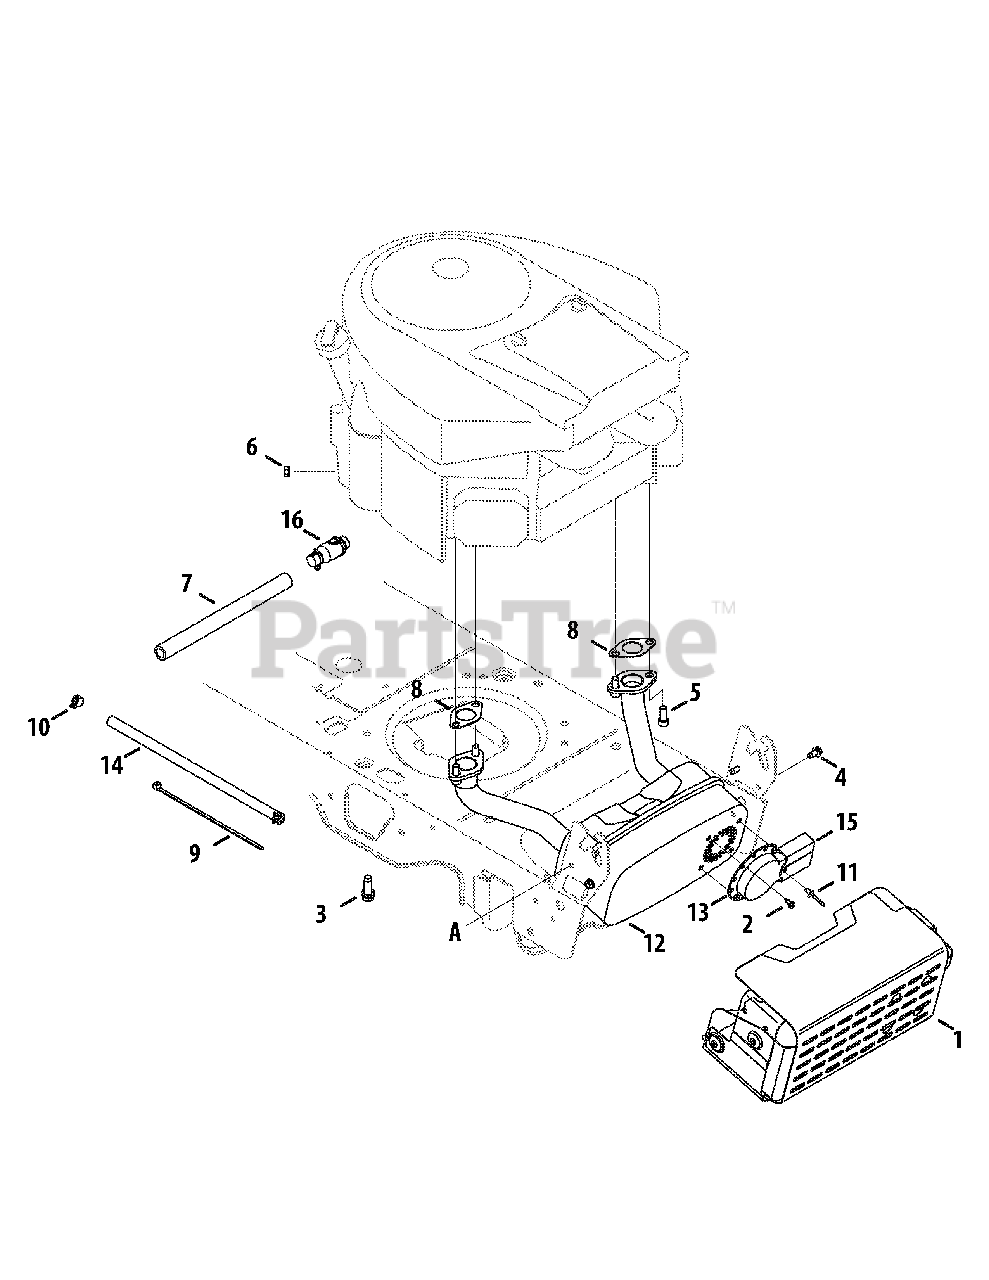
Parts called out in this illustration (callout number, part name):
1	Shield Ass’y, Muffler
2	Screw, Ab, #8-18, 0.500,
3	Screw, Self-tapping, 3/8-16, 1.000,
4	Screw, Self-tapping, 1/4-20, 0.500,
5	Screw, Socket Head, 5/16-18, .750
6	Nut, Sems, 1/4-20
7	Hose, Extension, Oil Drain
8	Gasket, Exhaust
9	Cable, Tie, 3/16 x .05 x 7.4
10	Clamp, Hose, .490 Dia.
11	Rivet, Pop, .188 Dia x .300
12	Muffler, Intek Twin
13	Deflector, Muffler
14	Hose, Fuel, Low Permeation, 1/4
15	Deflector, Muffler, Long
